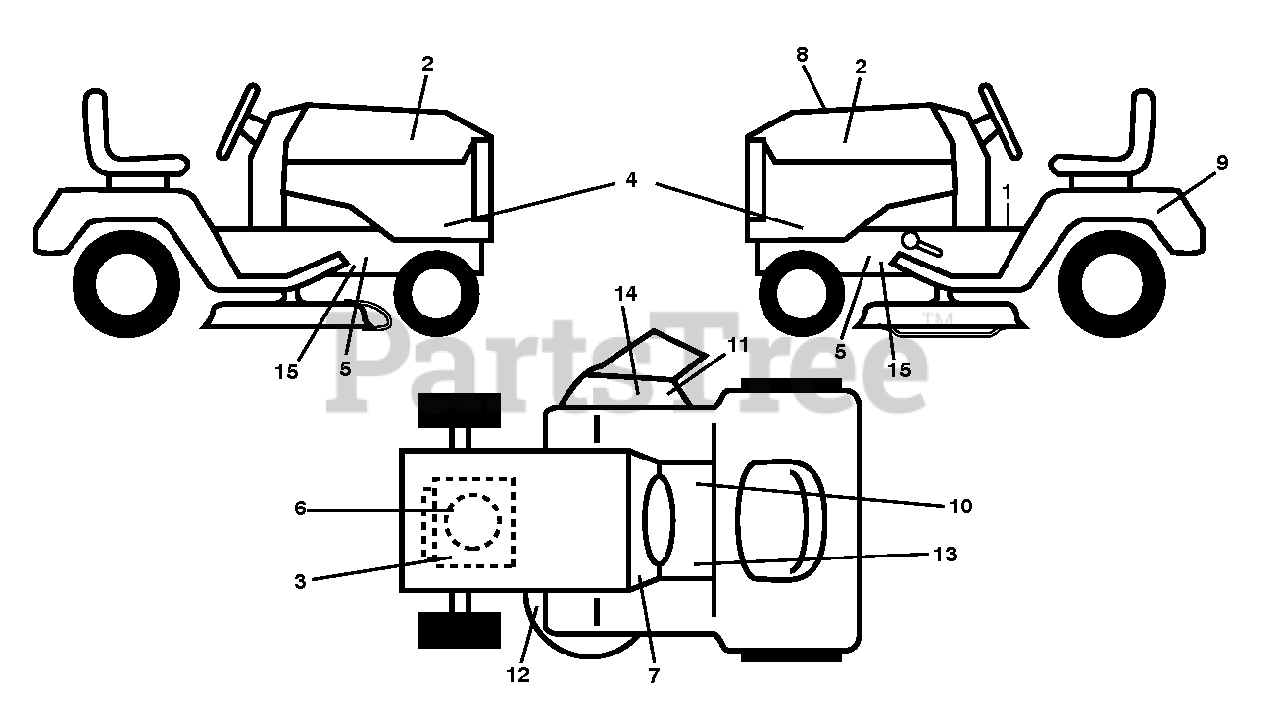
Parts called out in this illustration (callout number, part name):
1	DECAL.READ.OWN.MAN.SYMBOL.LT
2	DECAL.BADGE.170MM.TEXTLOGO.
3	DECAL.ENGINE.WARNING
4	DECAL.SDPNL.HUSQLT.TS242.HUSQ
5	DECAL.CHASSIS.HOT.MUFFLER
6	DECAL.ENG.BS.500CC.ENDR.382273
7	DECAL.SNOWFLAKE.MS498.HUSQ
8	DECAL.RPL.BSM31.ENDR.LT.42.K46
9	DECAL BTRY SYMBOLS
10	DECAL.PARKING.BRAKE.SADDLE.LT
11	DECAL.DFLCTR.WARNNG.CTFNGR.SYM
12	DECAL.V-BELT.SCH.42/46"MEC/ELE
13	DECAL.FNDR.SDLE.BRAKE.CLUTCH.6
14	DECAL, DECK DEFLECTOR, WARNING
15	DECAL.WARNING.SERVCE/FIRE
